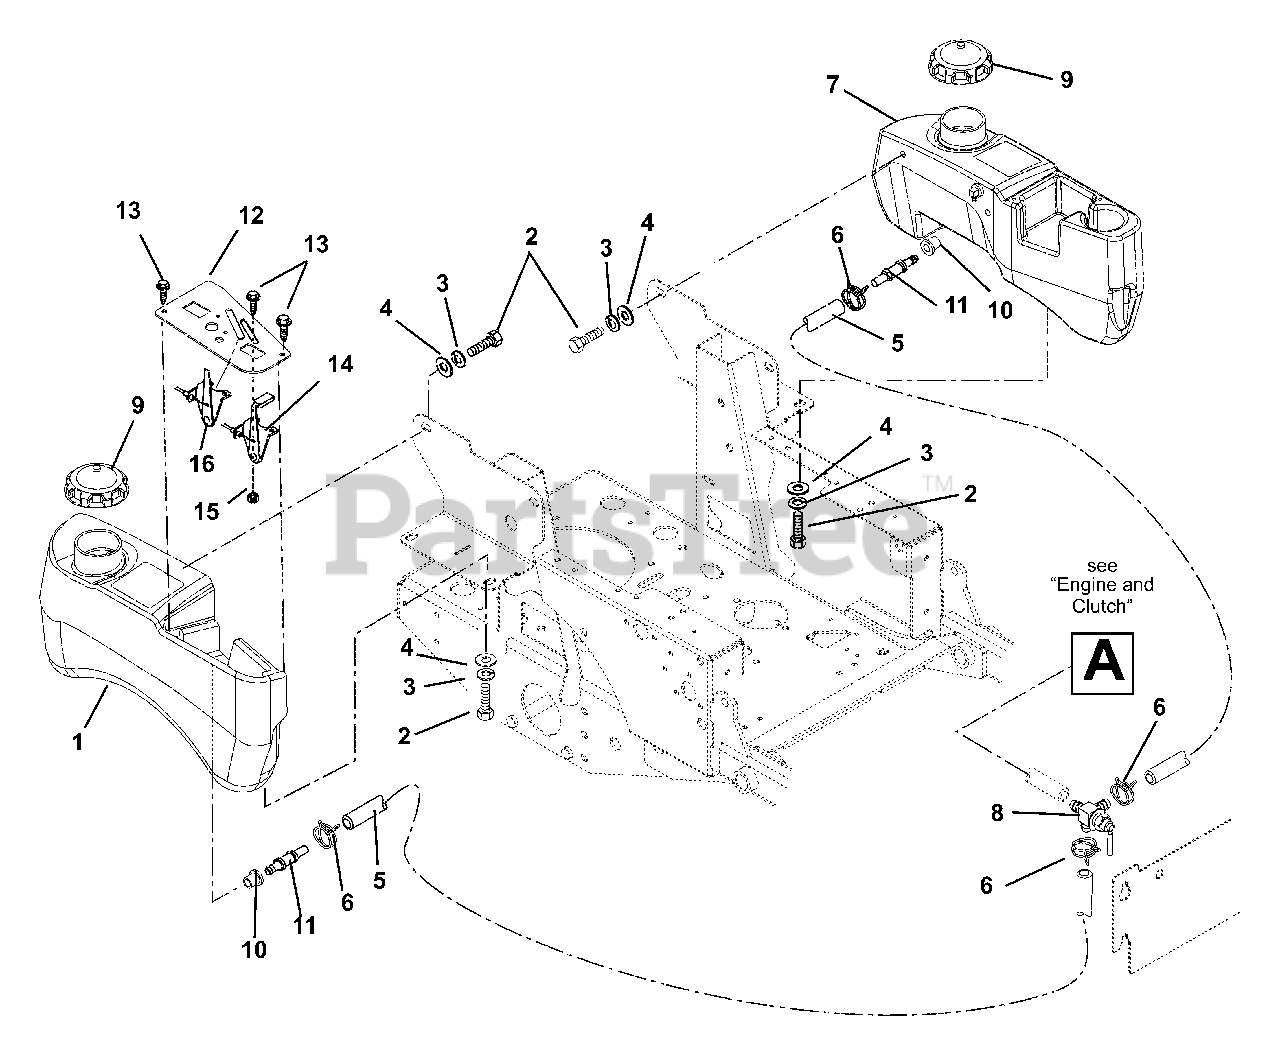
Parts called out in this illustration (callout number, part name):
1	TANK, FUEL RH W/O HOSE
2	@BLT-HEX .31-18X.75 GR5 YWZC
3	@WSHR-LK .31X.078 REG YWZC
4	@WSHR-FL-STL.38X.875X.083 YWZC
5	HOSE, 35"-1/4"ID GAS LINE
6	CLAMP-HOSE WIRE .490/.510X.116
7	TANK, LH FUEL CZ W/O HOSE
8	VALVE, FUEL
9	CAP - FUEL
10	BSHG-FLG .375 X 1.062 X .625 R
11	FITTING, TANK
12	PANEL, CONTROL
13	@SCR-MCH 10-24X.50 HWH YWZC
14	CABLE, THROTTLE-CHOKE
15	@NUT-LK-NYL 10-24 W/INSRT YWZC
16	CABLE, CHOKE
